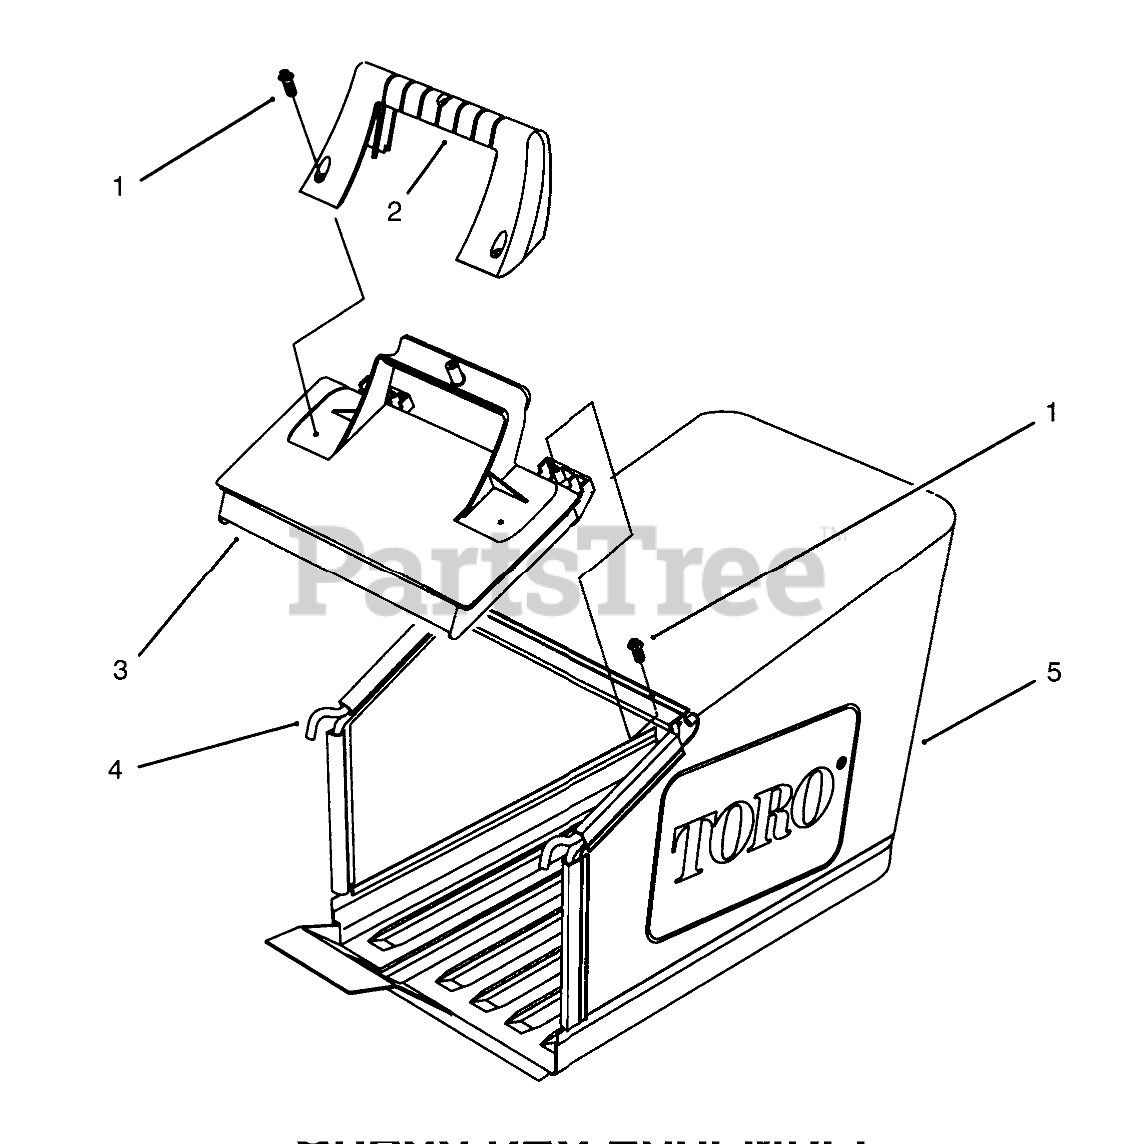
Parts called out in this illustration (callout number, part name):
1	SCREW-HWHTF
2	HANDLE-DOOR
3	DOOR-BAG
4	Frame
5	GRASS BAG 48CM W/PAN
